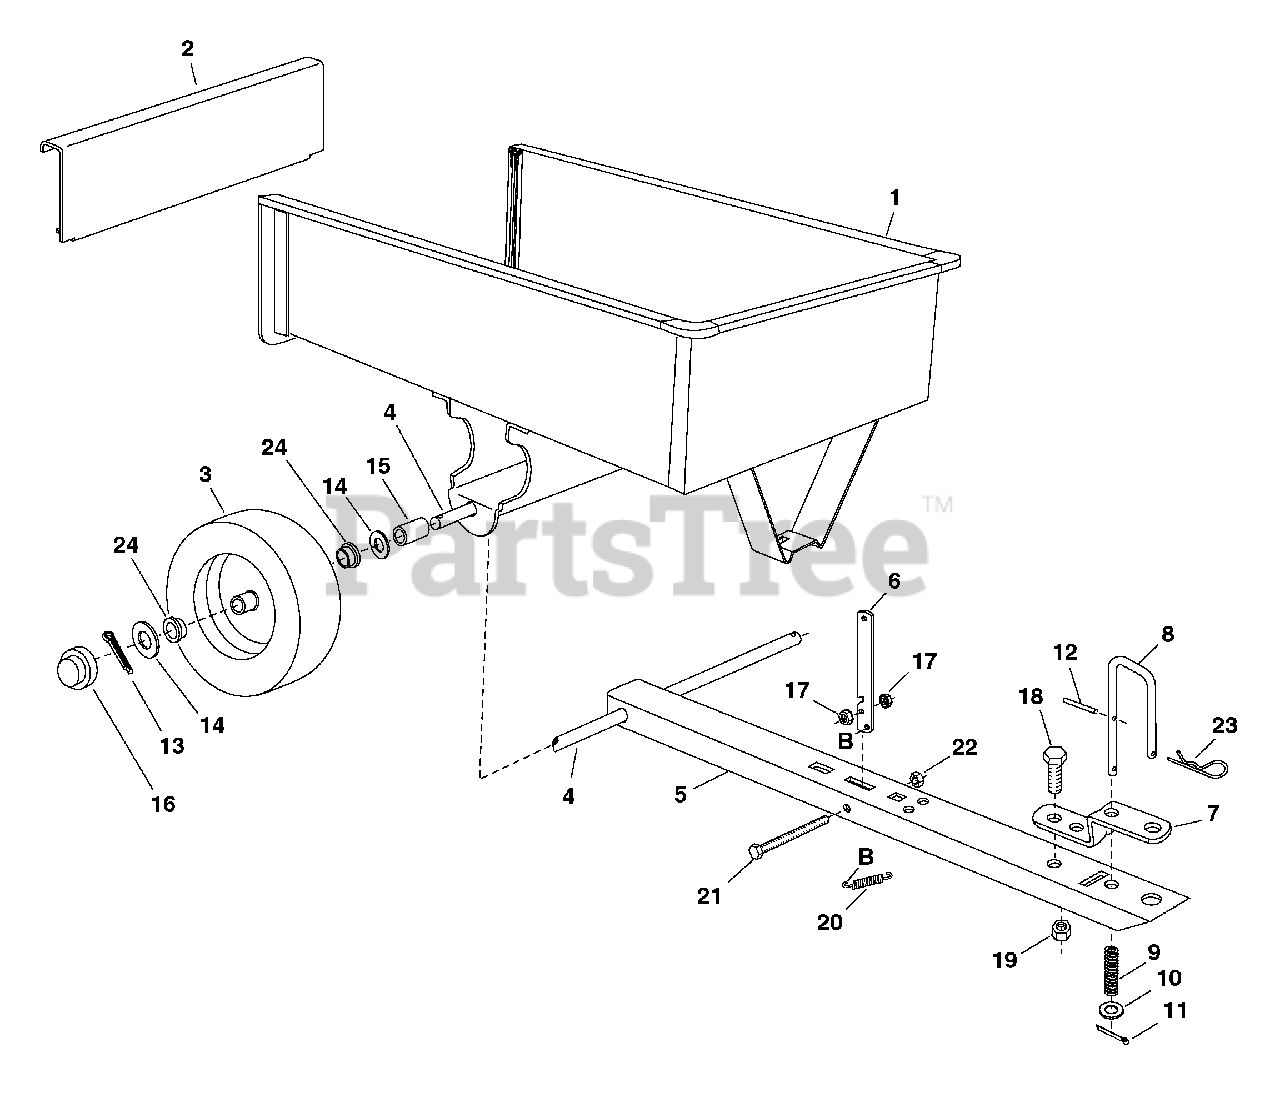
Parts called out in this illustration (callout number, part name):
1	Cart Body Assembly
2	Tailgate
3	Wheel, 15/6.00 x 8.00
4	Axle, Wheel 1" Dia.
5	Draw Bar Tongue
6	Latch Lock Lever
7	Hitch Bracket
8	Hitch Pin
9	Compression Spring
10	Washer, 3/8"
11	Cotter Pin, 1/8" x 3/4"
12	Spring Pin, 5/32" x 1-1/4"
13	Cotter Pin, 1/8" Dia. x 1-1/2"
14	Washer, Flat 1"
15	Spacer Tube
16	Hub Cap
17	Hex Nut, 5/16-18 (SEMS)
18	Hex Bolt, 3/8-16 x 1" Lg.
19	Nylock Nut, 3/8-16
20	Extension Spring
21	Hex Bolt, 5/16-18 x 3-3/4
22	Nylock Nut, 5/16-18
23	Hairpin Cotter
24	Wheel Bearing
